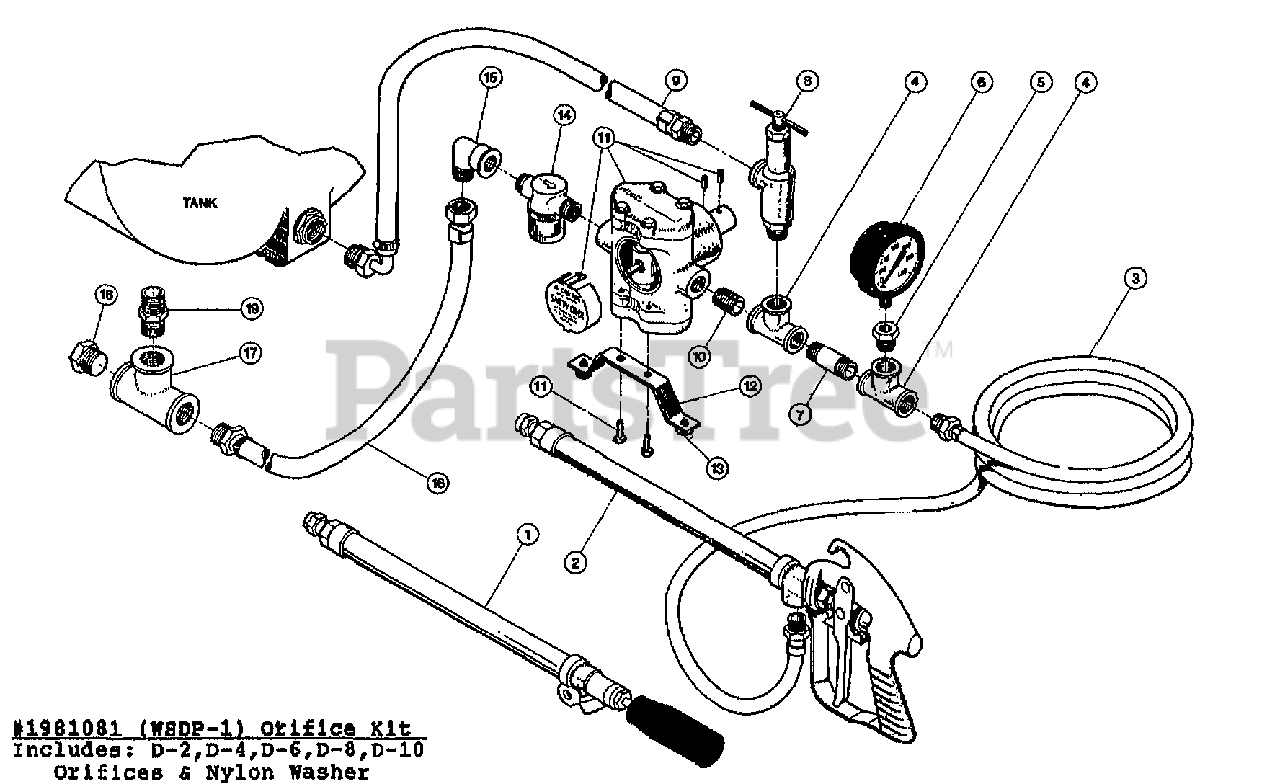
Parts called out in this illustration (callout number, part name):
1	GUN-TWIST SPRAY W143BR1/2
2	GRIP-PISTOL W43H6BR SPRAY GUN
3	HOSE-3/8 X 25' W2075660
4	TEE-1/2" PIPE W20983014
5	PIPE-BUSHING REDUCING
6	GAUGE-GLYCERINE PRESS WLFS220
7	NIPPLE-PIPE 50X2 GALVANIZED
8	VALVE PRESS.
9	HOSE-RETURN LINE W2075603
10	NIPPLE-1/2" CLOSE W20981014
11	PUMP-TWIN PISTON
12	ARM-TRQ 25G SPRAY W28200028
13	BUMPER-RUBBER TORQUE ARM
14	STRAINER W33500079
15	ELBOW-1/2" STREET WSE12
16	HOSE-17" SUCTION W2075661
17	TEE-3/4 PIPE NYL WTT34
18	PLUG-3/4" PLASTIC WF3400
19	NIPPLE-3/4 CLOSE WM1400
